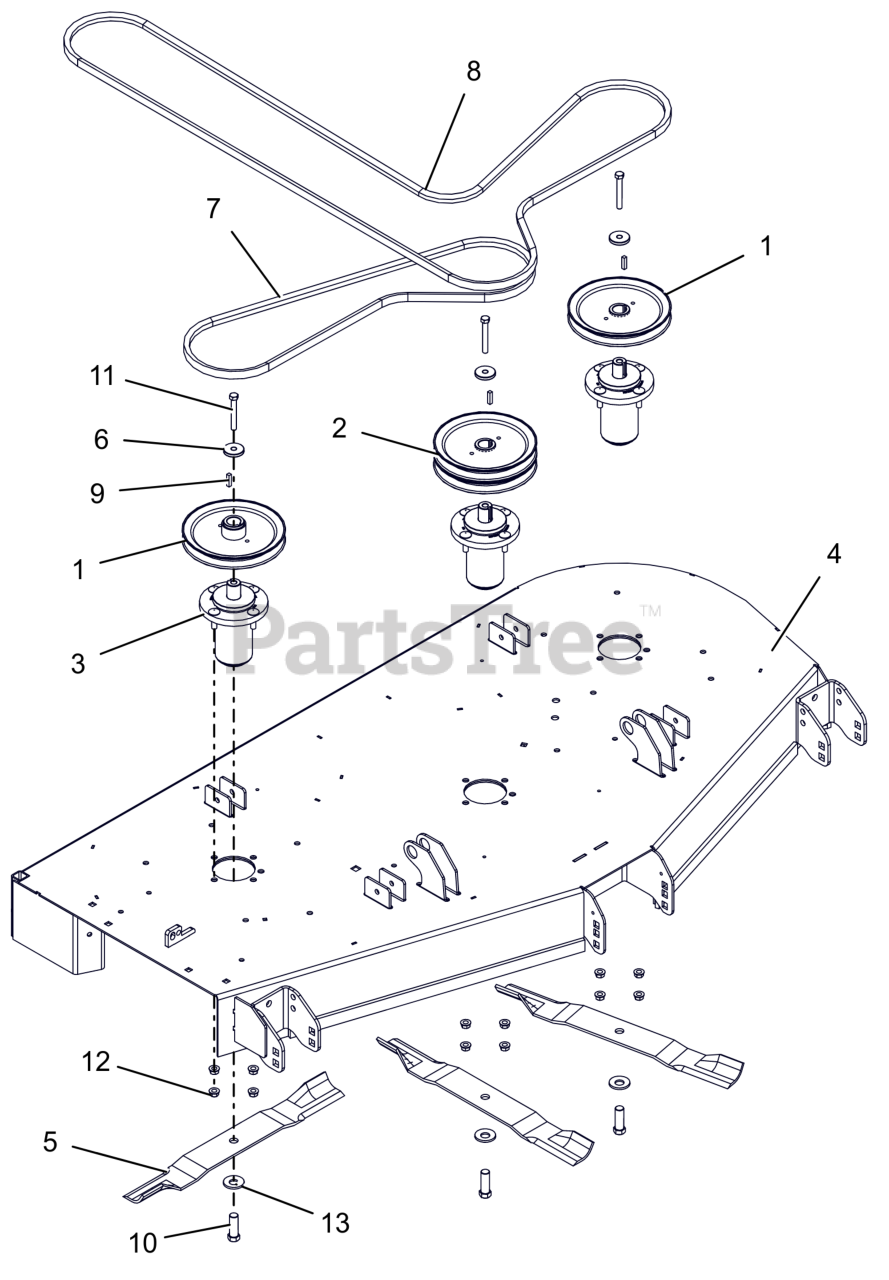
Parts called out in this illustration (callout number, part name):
1	PULLEY, V-7.50 OD X 1"ID
2	PULLEY, DOUBLE 1"X7.50"&7.50" (BLACK)
3	ASM, MAINT FREE ALUM SPINDLE
4	WLDMT, 60" CE SIDE DISCH DECK (ORANGE)
5	BLADE, 20.5"
6	RETAINER, SHEAVE
7	V-BELT, B-COGGED
8	V-BELT, HB SECTION
9	KEY, SQ .25X.25X1.00 RC 40-50
10	BLT, HEX .62-18X1.75 G8 ZCC
11	BLT, HEX .38-16X2.75 G8 ZCC
12	NUT-LK-CTR-FLG .375-16 GF ZCC
13	WSHR-BLVL .669X1.535X.138
